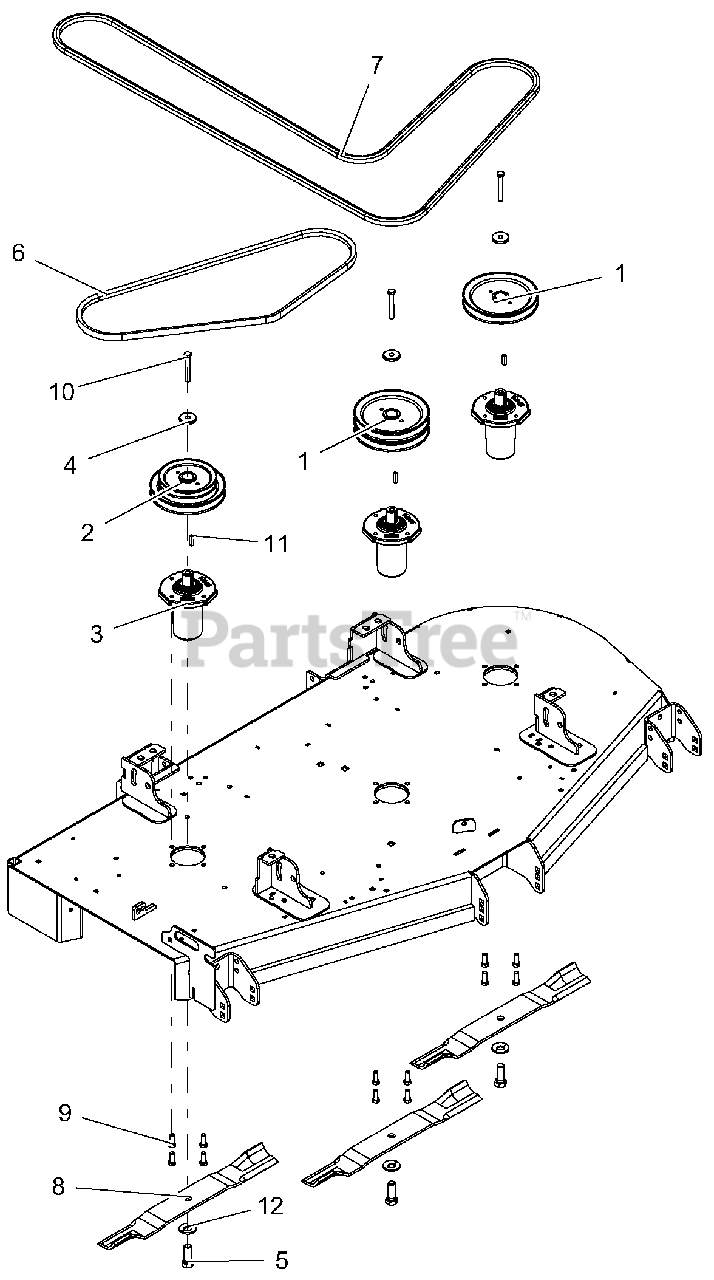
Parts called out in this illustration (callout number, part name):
1	PULLEY,
2	PULLEY, DOUBLE -1" ID X 6.75" & 5.25" OD
3	SERVICE, ASM SPINDLE- DUCTILE
4	RETAINER, SHEAVE SPINDLE
5	BLT, HEX .62-18X1.75 GR8 YWZC
6	BELT, B 63.00 RAW COGGED
7	BELT, BB 118.00 WRAPPED HEX
8	BLADE, MOWER 60"
9	BLT-HEX .38-16X1.00 GR5 YWZC EP30
10	BLT-HEX .38-16X2.75 GR8 YWZC
11	KEY-SQ .250X.250X1.00 RC 40-50
12	WSHR, BLVL .63X1.625X.14
